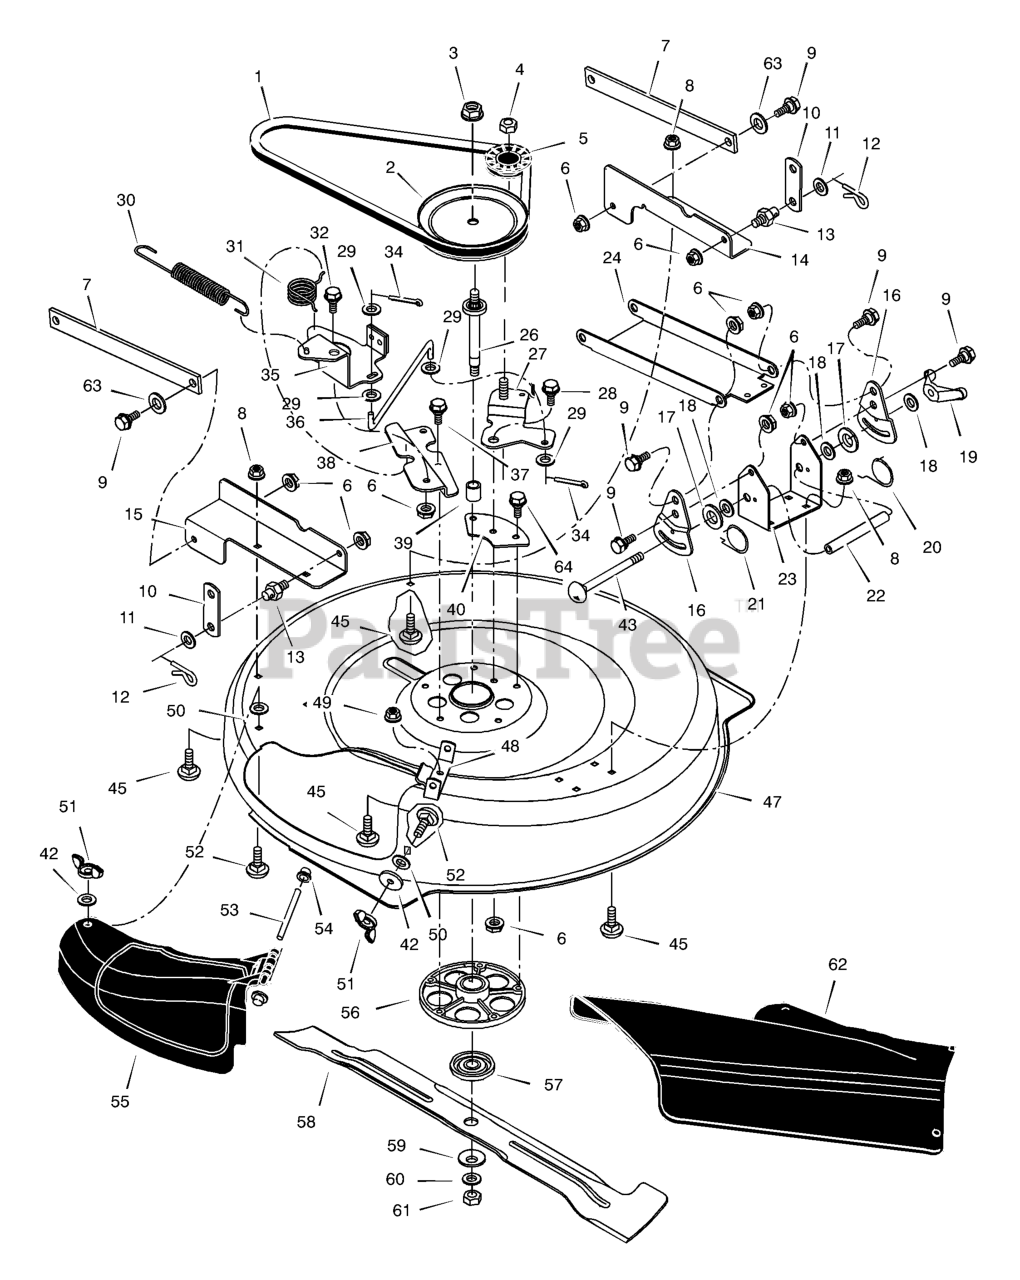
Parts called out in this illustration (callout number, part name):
1	Belt, Blade Drive
2	Pulley, Input
3	NUT, Nylock Ring, Pulley, 9/16-18
4	NUT, Hex Flange, Center Lock, 3/8-16
5	IDLER PULLEY, Fixed
6	NUT, Hex Flange, Center Lock, 3/8-16
8	NUT, Hex Flange, 5/16-18
9	BOLT, Shoulder
10	Link, Lift
11	WASHER, 1/2 x 7/8
12	PIN, Hair
13	PIN, Threaded, Shoulder, 3/8-16 x 1-7/16 Long
14	Bracket, Left Rear
15	Bracket, Right Rear
16	Plate, Adjustment
17	FRICTION PAD
18	WASHER, Flat, 1
19	WINGNUT 5/16-18
20	SPRING, Left Torsion
21	SPRING, Right Torsion
22	Tube, Spacer
23	Bracket, Deck
24	Hanger, Front
26	Shaft, Splined
27	Arm Assembly , Idler
28	BOLT, Shoulder, 3/8-16 x 1/2
29	WASHER, Flat, 5/16
30	SPRING, Extension
31	Spring, Torsion
32	BOLT, Shoulder, 3/8-16 x 3/5
34	COTTERPIN, 3/4
35	Arm Assembly, Brake
36	Link, Idler Arm
37	SCREW, Self Tap, 3/8-16 x 1-1/4
38	Bracket, Brake Mounting
39	Spacer, Jackshaft
40	Plate, Idler Mounting
43	Bolt, Carriage
45	BOLT, Carriage, 5/16-18 x 5/8
47	Housing, Blade
48	Hinge, Mulching Cover
49	NUT, Hex Flange, Center Lock, 5/16-18
50	NUT, Push, 1/4
51	NUT, Wing, 5/16-18
52	BOLT, Carriage, 5/16-18 x 3/4
53	Rod, Chute Deflector
54	CAP, Push On
55	Cover, Mulch (Black)
56	ASM. JACKSHAFT HOUSING W/VENTS
57	Adapter, Deck/Blade
59	WASHER, Belleville
60	WASHER, Hardened
61	NUT, Blade, 9/16-18
62	Deflector, Chute (Black)
63	WASHER, 1/2 x 1-1/2
64	SCREW, Self Tap, 3/8-16 x 1-1/4
